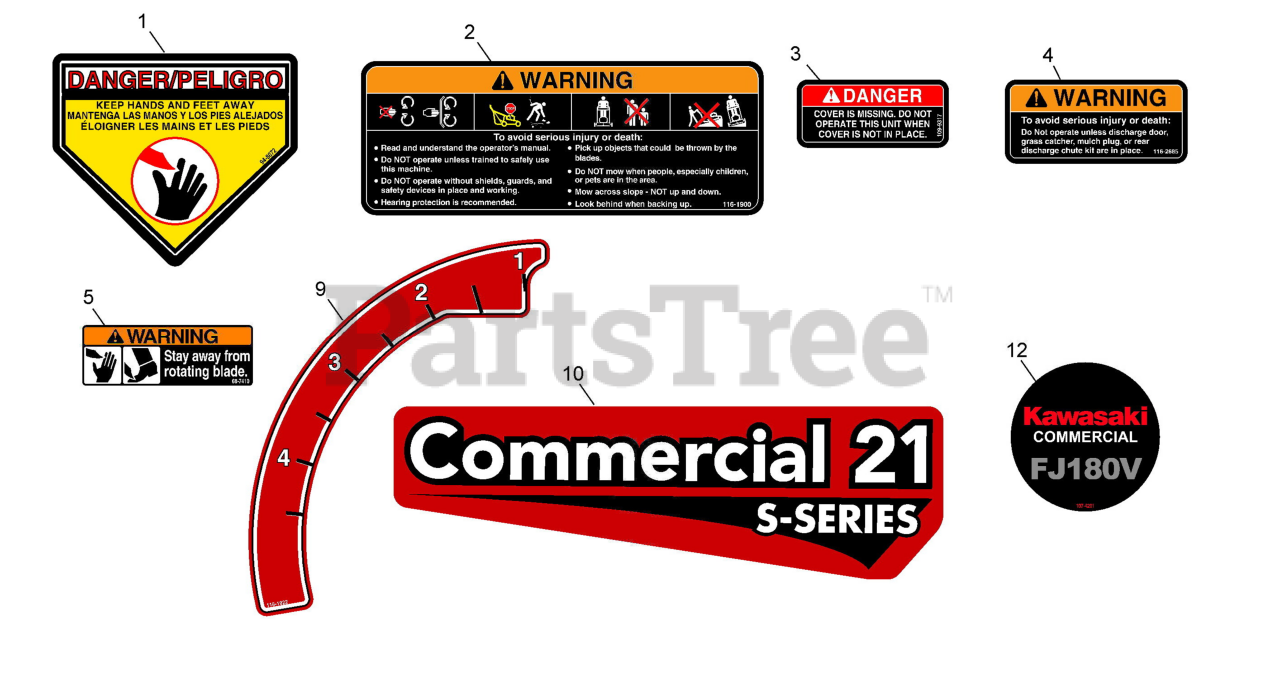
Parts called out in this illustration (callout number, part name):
1	DECAL-DANGER
2	DECAL-WARNING
3	DECAL-COVER MISSING
4	DECAL-WARNING DOOR SM
5	DECAL-BLADE
9	DECAL-HEIGHT OF CUT
10	DECAL-COMM 21 S-SERIES
12	DECAL-RECOIL
